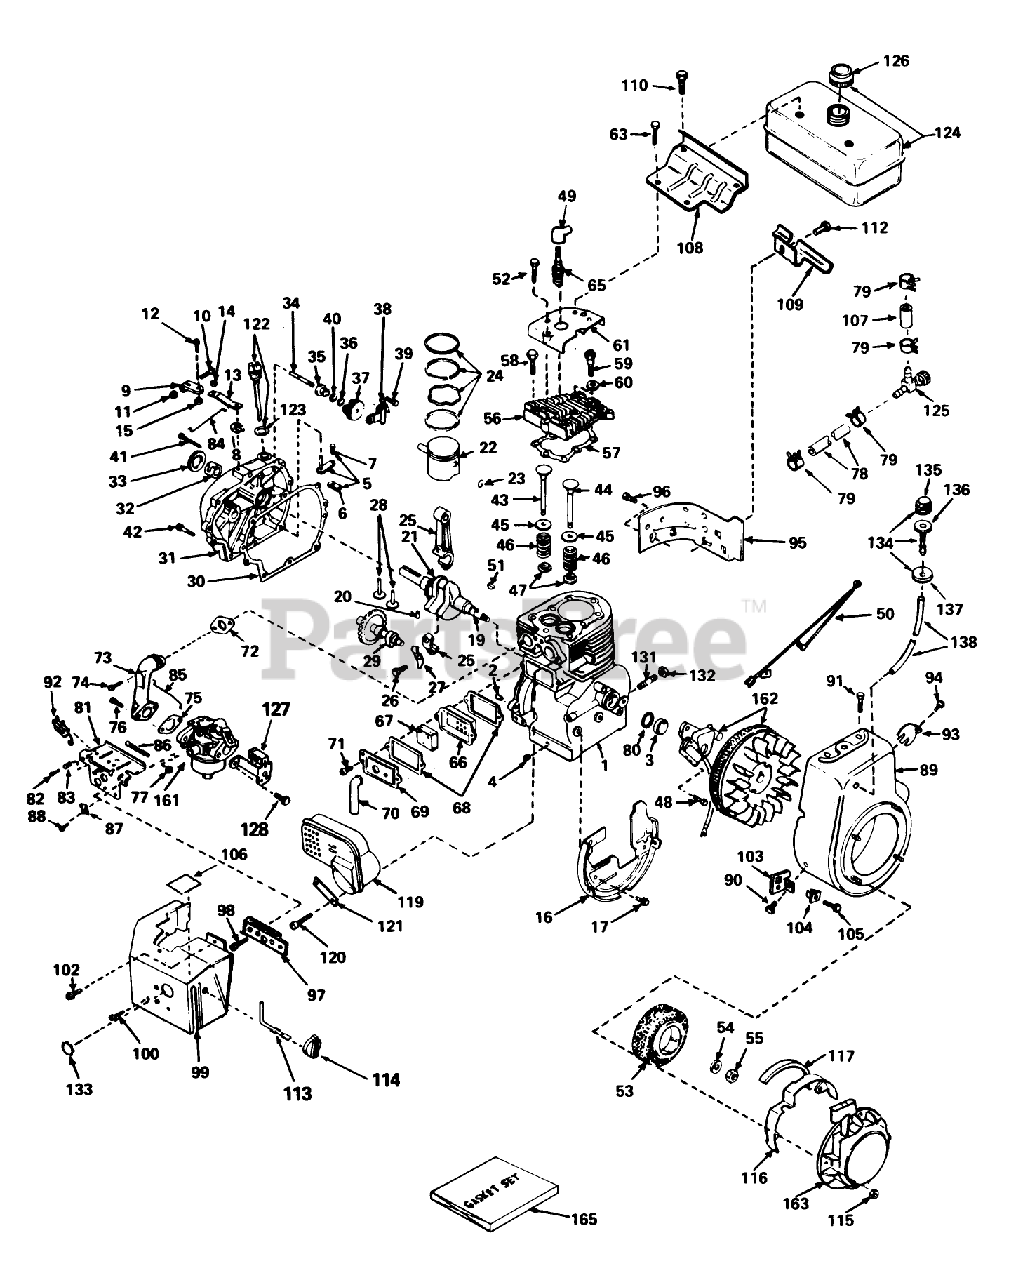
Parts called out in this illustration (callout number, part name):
1	Cylinder Assembly (Incl. Ref. #2, 3 4)
2	Pin-Dowel
3	Oil Seal
4	Plug-Drain, Oil (SQH 1/4-18)
5	Rod, Governor (Incl. Nos.62 63)
6	Yoke-Governor
7	Screw (6-40x5/16)
8	Ring-Retaining
9	Clamp-Lever, Governor
10	Screw
11	Nut-Lock
12	Screw
13	Lever-Governor
14	Washer-Lock
15	Nut-Lock
16	Baffle Blower Housing
17	Screw (1/4-20x19/32)
19	Crankshaft Assy. (Incl. Nos. 20 21)
20	Pin, Groove
21	Gear, Crankshaft
22	Piston Pin Assy. (Std.) (Incl. Ref. #26)
22	Piston, Pin Ring Assy.(Std.) (Incl. Ref. #24A, 25 26)
22	Piston Pin Assy. (.010 oversize) (Incl. Ref. #26)
22	Piston, Pin Ring Assy. (.010 oversize) (Incl. Ref. #24A, 25 26)
22	Piston Pin Assy. (.020 oversize) (Incl. Ref. #26)
22	Piston, Pin Ring Assy. (.020 oversize) (Incl. Ref. #24A, 25 26)
24	Ring Set (Std.)
24	Ring Set (.010" OS)
24	Ring Set (.020" OS)
25	Rod Assy., Connecting (Incl. Nos. 10 18)
26	Bolt, Connecting Rod
27	Dipper-Oil
28	Lifter-Valve
29	Camshaft (Mech. Comp. Release)
30	Gasket, Cylinder Cover
31	Cover, Cylinder (Incl. Ref. #32, 33 34)
32	Bushing, Crankshaft
33	Seal, Oil
34	Shaft-Governor
35	Spool-Governor
36	Ring-Retaining
37	Governor Gear ASM
38	Bracket-Gear, Governor
39	Screw (10-32 x 35/64)
40	Washer-Flat
41	Screw (1/4-20 x 1-1/4)
42	Screw
43	Valve, Intake (Std.) (Incl. Ref. #58)
43	Valve, Intake (1/32" oversize) (Incl. Ref. #58)
44	Valve, Exhaust (Standard)(Incl. No. 9)
44	Valve, Exhaust (1/32" oversize)(Incl. No. 9)
45	Cap-Spring, Valve
46	Spring-Valve
47	Keeper-Spring, Valve
48	Screw
49	Cover-Spark Plug
50	Wire, Ground
51	Key-Flywheel
52	Screw (1/4-20 x 1/2)
53	Hub Screen Assy., Starter
54	Washer
56	Head Cylinder
57	Gasket-Cylinder Head
58	Screw (5/16-18x1-1/2)
59	Screw (5/16-18x1-25/32)
60	Washer-Flat
61	Cover, Cylinder Head
63	Screw
65	Plug, Spark (J17LM or equiv.)
65	Plug, Spark (Champion RCJ-8)
66	Body-Breather
67	Element-Breather
68	Gasket-Breather
69	Cover-Valve
70	Tube-Breather
71	Screw
72	Gasket-Intake
73	Pipe-Intake
74	Screw (T-30, 5/16-18x1-3/32)
75	Gasket, Carburetor
76	Screw (1/4-28x1)
77	Nut and Lock Washer (1/4-28)
78	Line-Fuel
79	Clamp-Line, Fuel
80	Gasket Stator
81	Control Assy., Speed (Incl. Ref. #82, 83, 86 92)
82	Screw
83	Spring-Compression
84	Link, Governor
85	Link-Throttle
86	Spring, Extension
87	Conduit
88	Screw (10-32 x 3/8)
89	Housing, Blower
90	Screw, Hex Hd.
91	Screw (5/16-18x3/4)
92	Terminal Assembly
93	Screw
94	Screw (8-32 x 3/8)
95	Extension, Blower Housing
96	Screw
97	Bracket-Carburetor
98	Screw (8-32x27/64)
99	Cover, Carburetor
100	Screw (10-32 x 3/8)
102	Screw (10-32x1/2)
103	Bracket
104	Grommet
105	Screw
107	Line-Fuel (8.62)
108	Plate, Fuel Tank Mounting
109	Bracket-Tank, Fuel
110	Screw (1/4-15x7/8)
112	Screw (1/4-20x19/32)
113	Rod-Choke
114	Knob-Control
115	Nut and Lock Washer (1/4-28)
116	Guard, Starter
117	Seal, Snowguard
119	Muffler
120	Screw, Hex Hd.
121	62513 SNWTHWR W/284
122	Dipstick, Oil (Incl. No. 30)
123	Gasket
124	Tank Assy., Fuel (Incl. No. 115)
125	Valve-Shut Off
126	Cap, Fuel
127	Bracket-Choke
128	Screw (10-32 x 1/2)
133	Plug
134	Primer Assy. (Incl. Nos. 89, 90 91)
135	Bulb, Primer
136	Body, Primer
137	Retainer, Primer Bulb
138	Line, Primer
161	Carburetor (Incl. Ref. #75)
162	Magneto (The complete magneto is not available as an assembly. The magneto number is shown for reference purposes only. Order component parts individually, as shown in parts list.)
163	Starter, Rewind
165	Gasket Set
